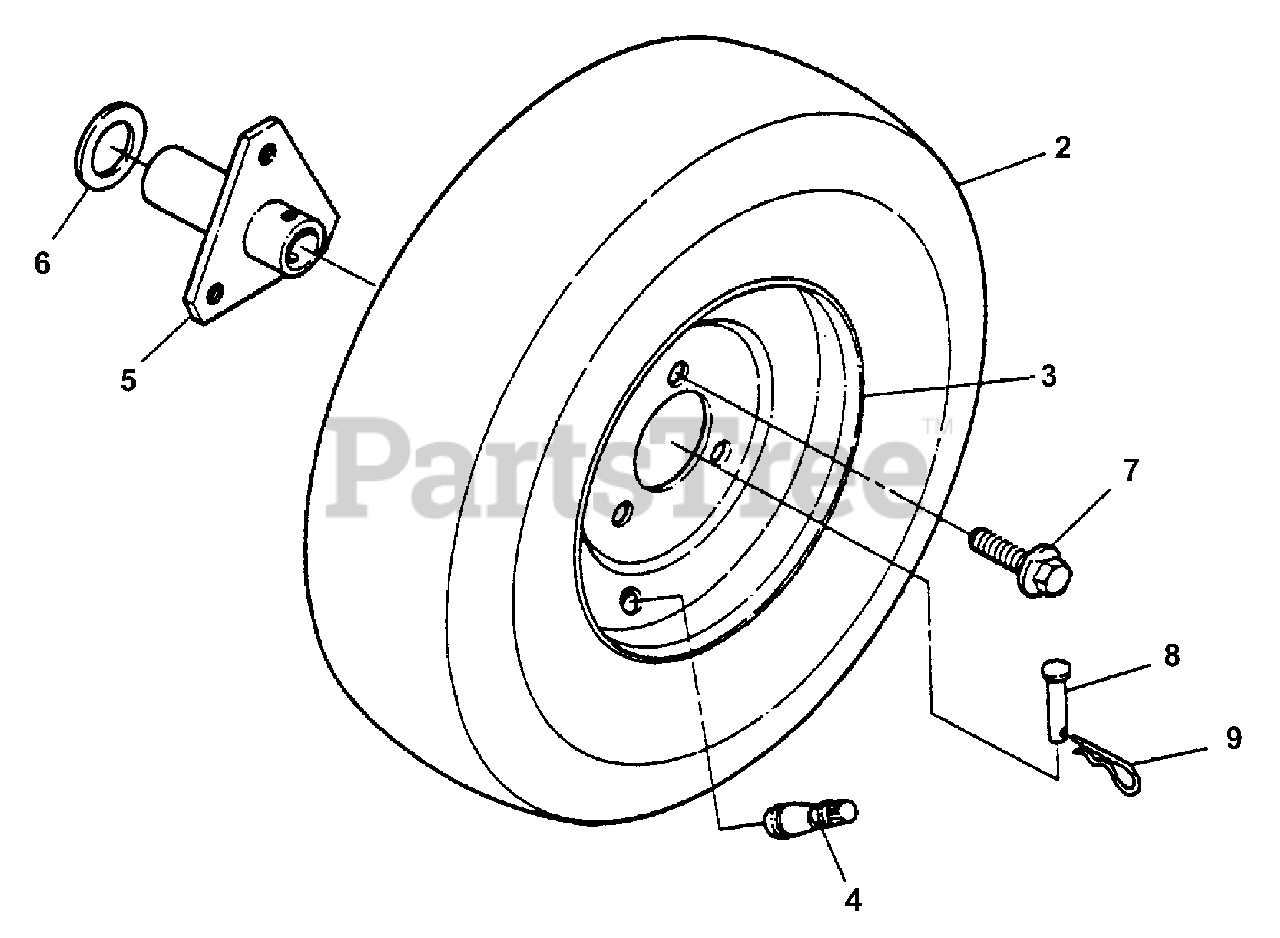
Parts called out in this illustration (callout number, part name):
2	TIRE, 16 x 4.80 x 8 (Snow Hog)
2	TIRE, 16 x 6.50 x 8 (Snow Hog)
3	WHEEL/RIM, 4.80/4.06x8 (3 hole)
3	WHEEL/RIM, 5.375x8 (3 hole)
4	VALVE, Snap-In
5	HUB, Wheel (weldment)
6	WASHER, 3/4 x 1-1/8" Thrust
7	BOLT, 1/2-20 x 3/4" Hex Head Lug (Nyloc) Grade 5
8	PIN, 5/16 x 1-11/16" Clevis
9	PIN, 3/32 x 1-1/2" Hair
